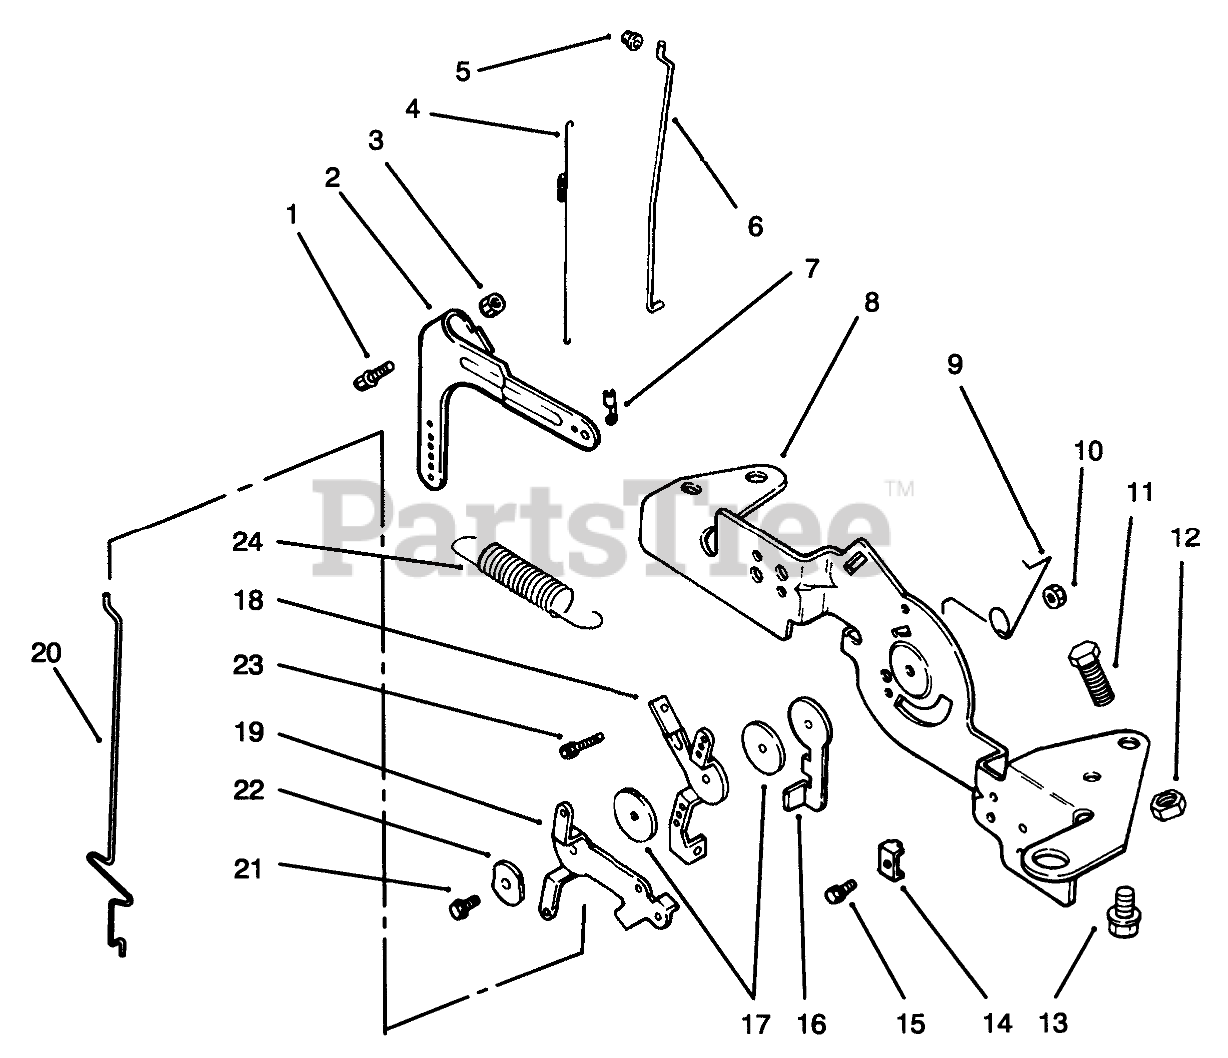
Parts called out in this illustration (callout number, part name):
1	Screw
2	Lever-Govenor
3	Nut
4	Spring-Linkage
5	Bushing-Linkage
6	Linkage-Throttle
7	Bushing-Linkage
8	Bracket-Control
9	Spring-Choke Return
10	Nut
11	Screw
12	Nut
13	Screw
14	Clamp
15	Screw
16	Lever-Actuator, Throttle
17	Washer
18	Lever-Throttle Control
19	Lever-Choke
20	Linkage-Choke
21	Screw
22	Washer-Wave
23	Screw-Hex.
24	Carriage Bolt
